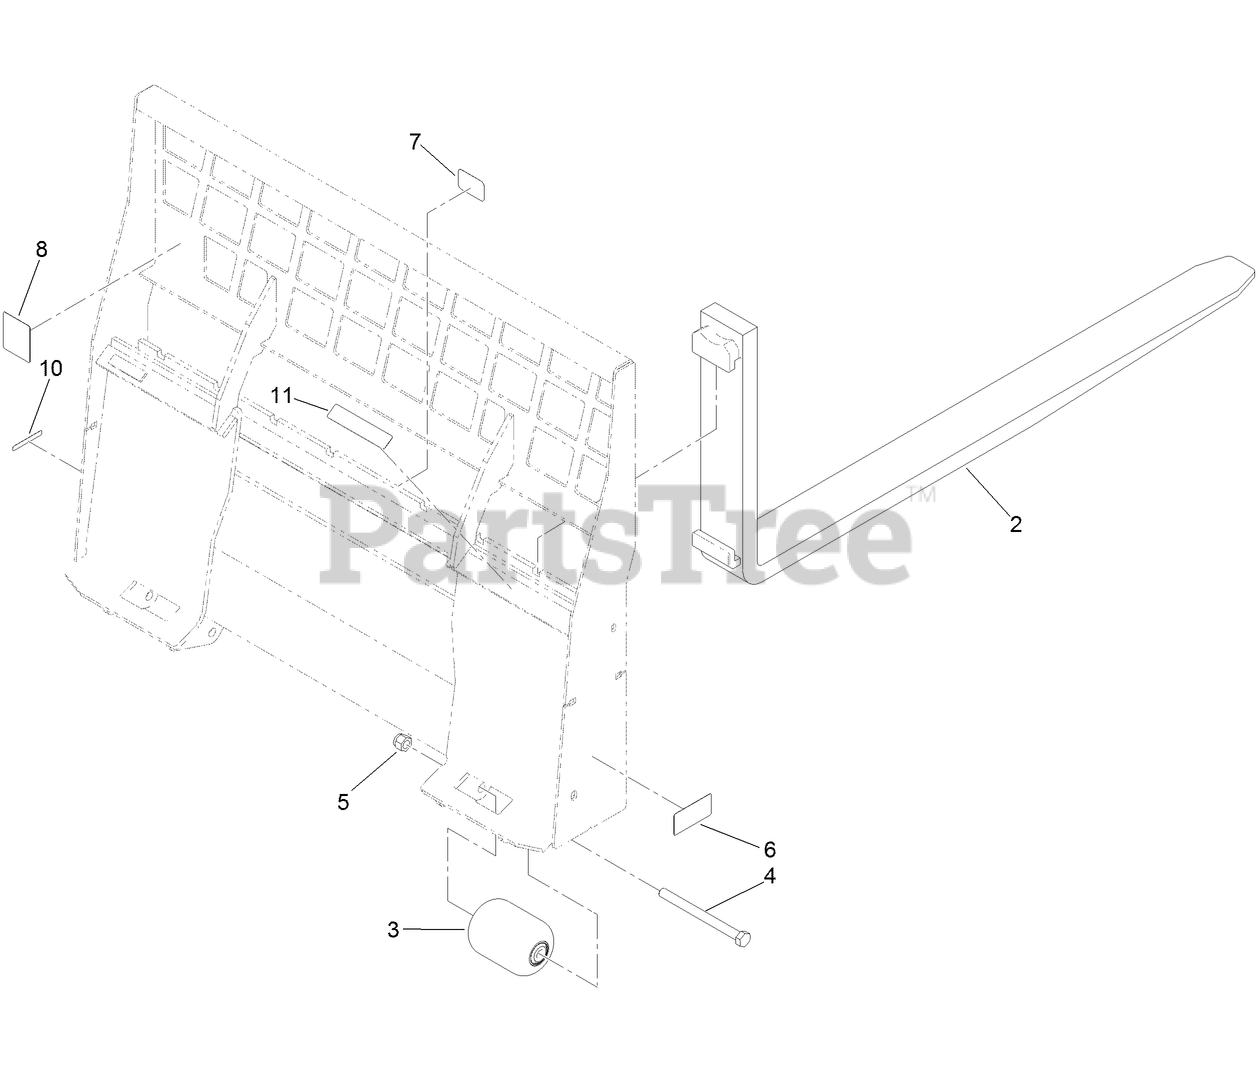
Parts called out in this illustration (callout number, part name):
3	ROLLER
4	SCREW-HH
5	NUT-LOCK, NI
6	DECAL-DANGER
7	DECAL
8	DECAL-CAPACITY
10	DECAL-WARNING
